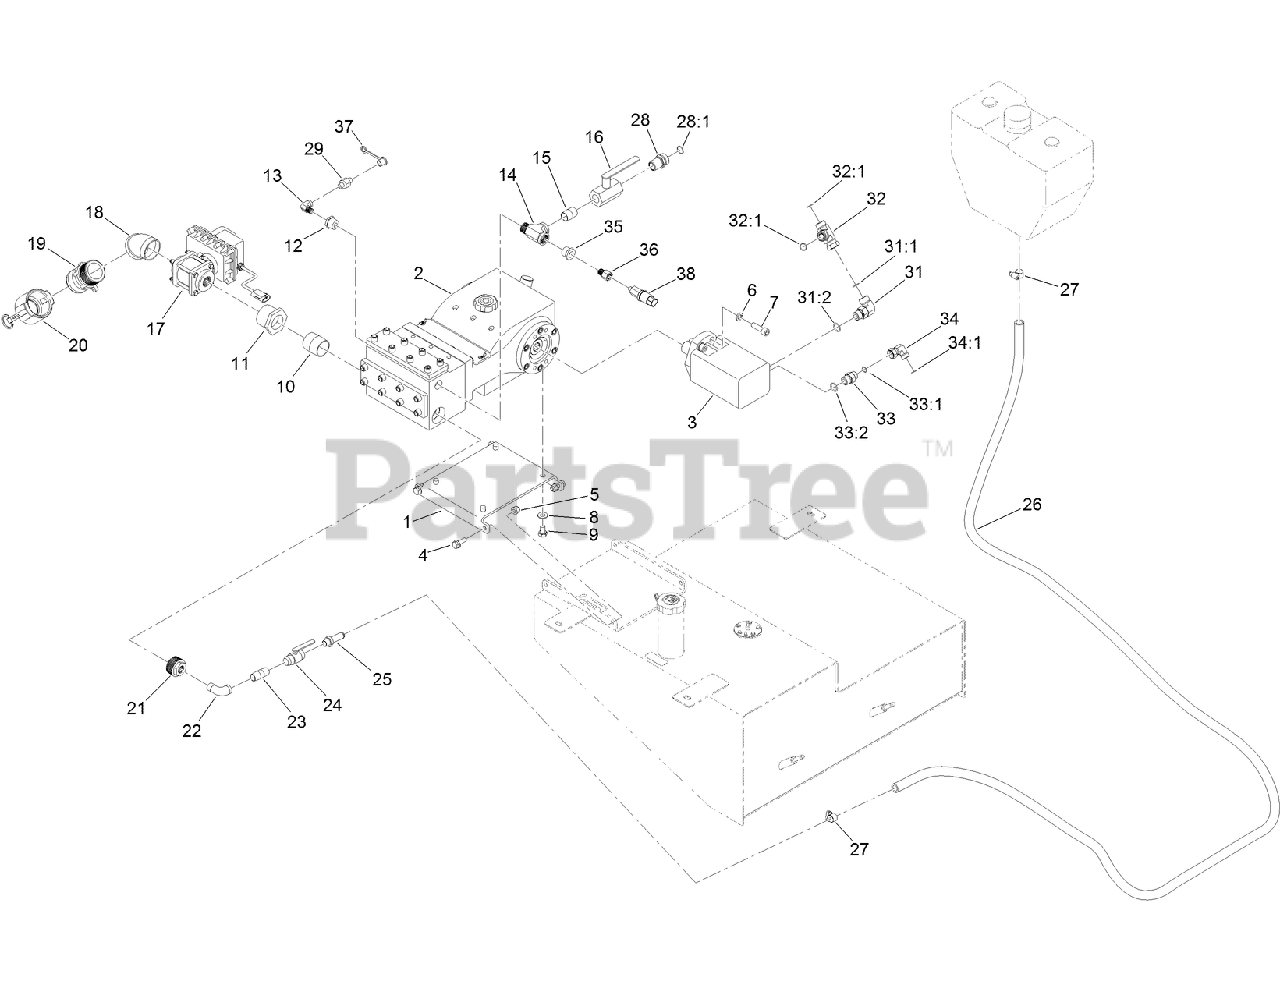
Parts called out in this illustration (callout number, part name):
1	PLATE-MOUNT, MUD PUMP
2	MUD PUMP ASM
3	HYD MOTOR ASM
4	SCREW-HHF
5	NUT-LOCK, NI
6	WASHER-LOCK
7	SCREW-HSH
8	WASHER-FLAT
9	BOLT-HH
10	NIPPLE-PIPE
11	BUSHING-REDUCER
12	BUSHING-REDUCER
13	FITTING-ELBOW-90
14	FITTING-TEE
15	NIPPLE-STRAIGHT
16	VALVE-BALL
17	2 INCH BALL VALVE ASM (ELECTRIC)
18	ELBOW-PIPE-45
19	ADAPTER-MALE
20	CAP-CONNECT, QUICK
21	BUSHING-PIPE, REDUCER
22	FITTING-ELBOW-90
23	NIPPLE-PIPE
24	VALVE-BALL
25	ADAPTER
26	HOSE-COOLANT
27	CLAMP-HOSE, WORM DRIVE
28	FITTING-STRAIGHT
28:1	O-RING
29	NIPPLE-CONNECT, QUICK
31	FITTING-ELBOW-90
31:1	O-RING
31:2	O-RING
32	FITTING-HYD, TEE
32:1	O-RING
33	Fitting
33:1	O-RING
33:2	O-RING
34	FITTING-HYD
34:1	O-RING
35	BUSHING-REDUCER
36	FITTING-STRAIGHT
37	CAP-DUST
38	TRANSDUCER (W/ISOLATOR)
